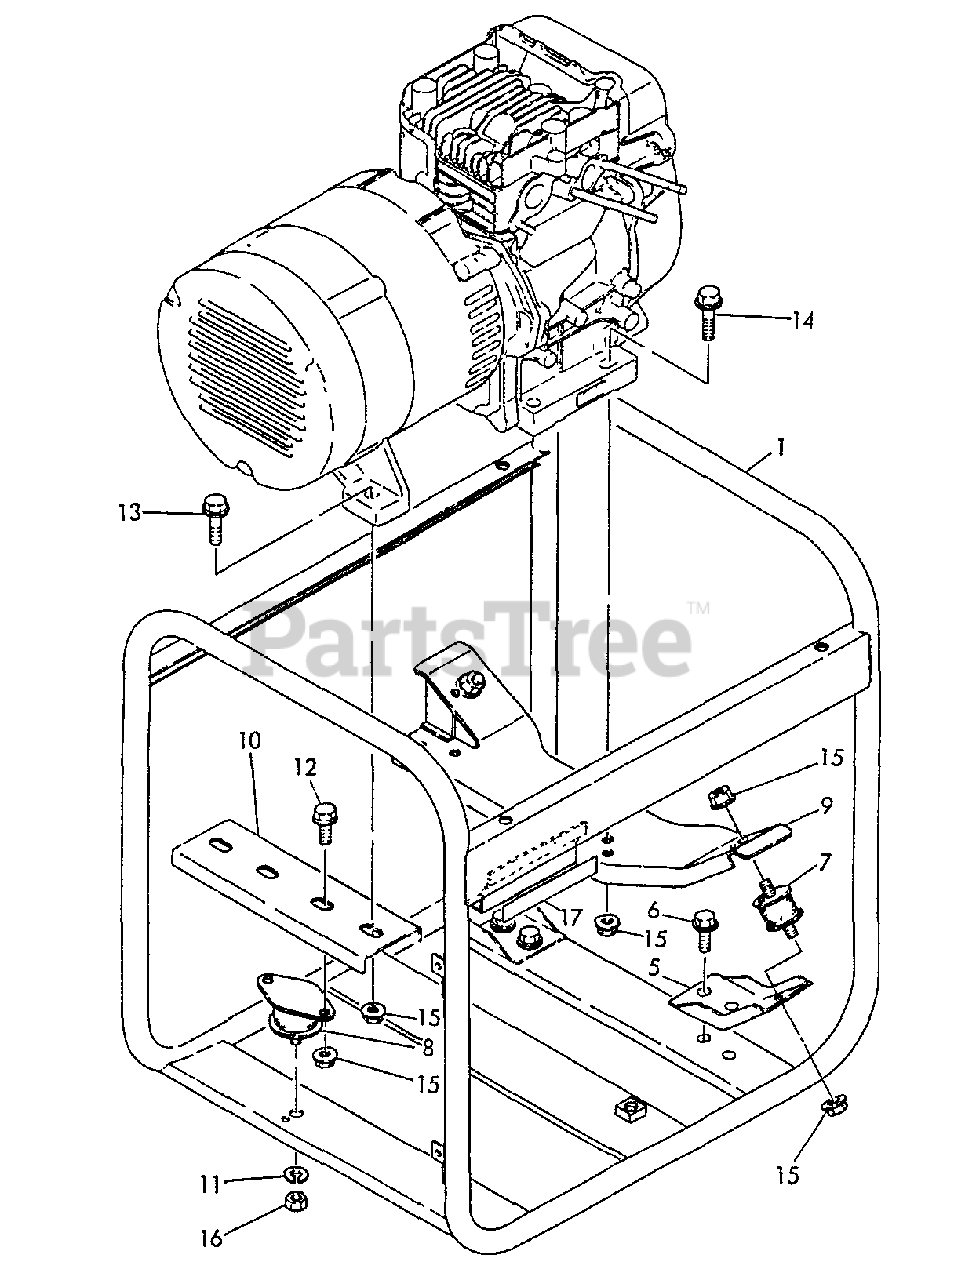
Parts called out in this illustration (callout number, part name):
1	FRAME ASSY
5	DAMPER STAY, LOWER
6	BOLT - 8×16 -- PLATED
7	DAMPER, FRONT
8	DAMPER
9	STAY, DAMPER
10	STAY, REAR DAMPER
11	LOCKWASHER - 10
12	BOLT - 8×20 -- PLATED
13	BOLT - 8×30 -- PLATED
14	BOLT - 8×38 -- PLATED
15	U-NUT M8
16	NUT - 10
17	SHEET, FRAME
